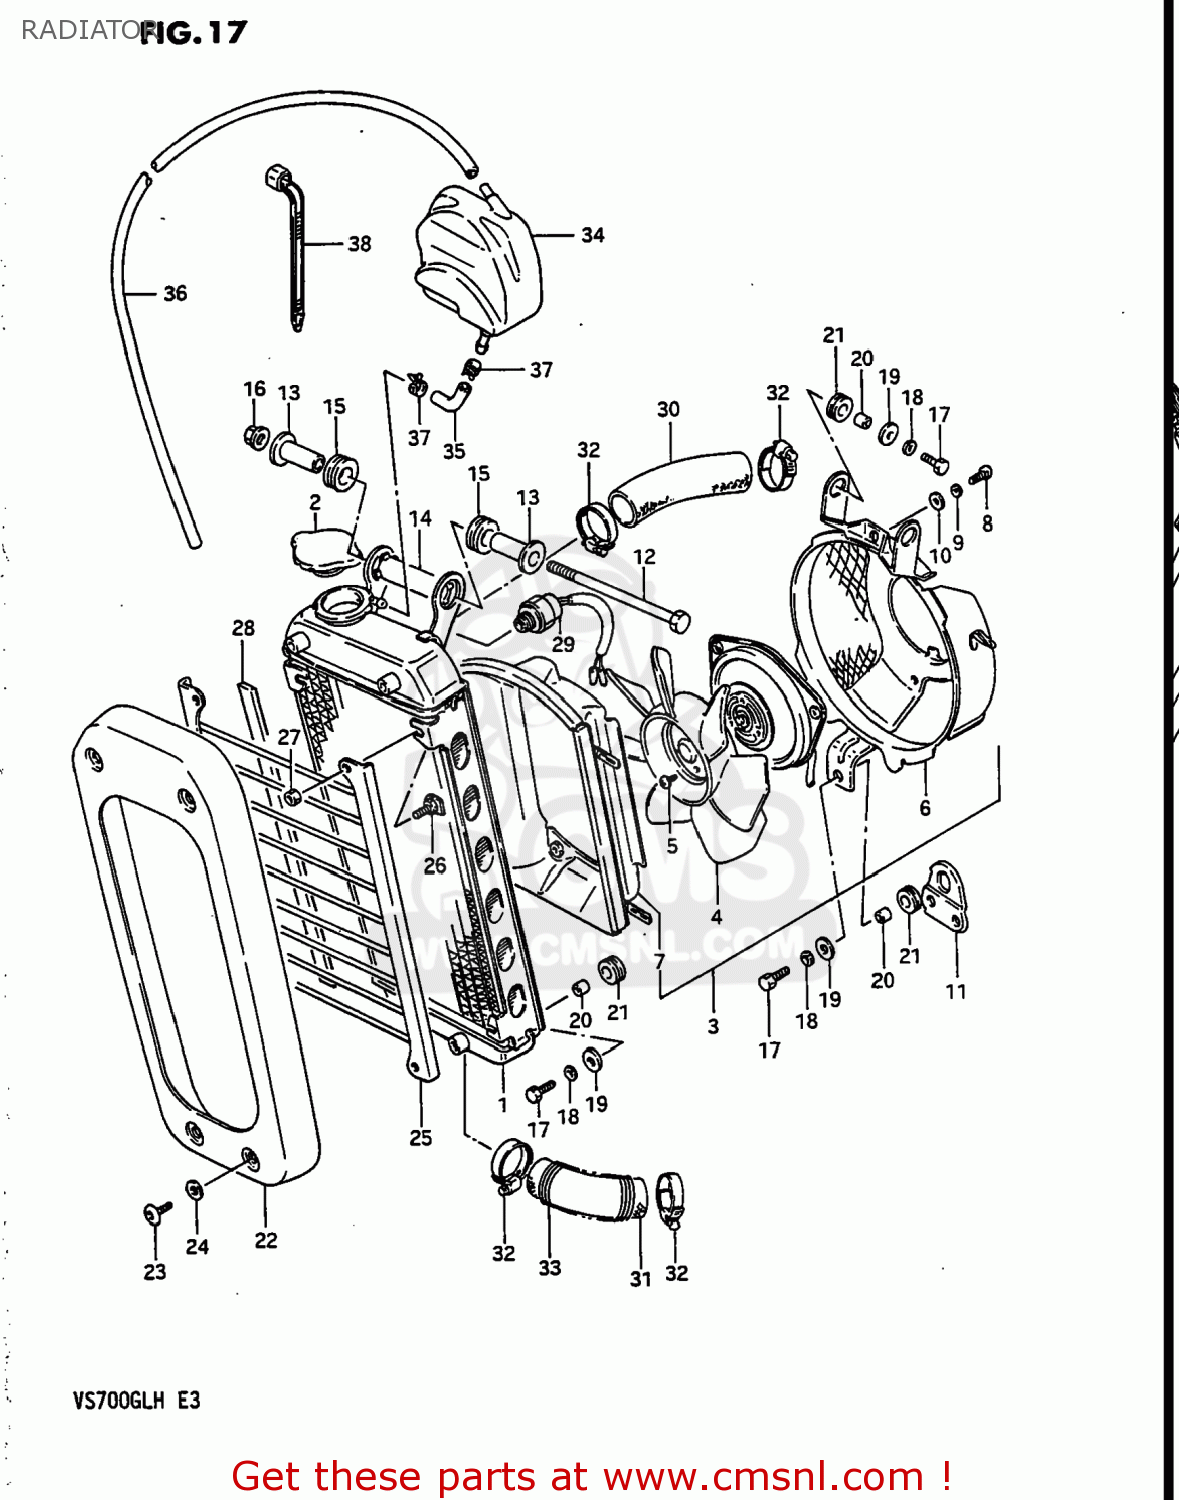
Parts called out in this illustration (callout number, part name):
1	RADIATOR COMP,WATER
2	CAP,RADIATOR
3	FAN ASSEMBLY,RADIATOR
4	FAN
5	BOLT
6	SHROUD,FAN
7	DUCT,FAN
8	SCREW 5X10
9	LOCK WASHER
10	WASHER
11	BRACKET,RADIATOR FAN
12	BOLT 10X135
13	SPACER,RADIATOR CUSHION
14	SPACER,RDTR CUSH NO.2 OUTER
15	CUSHION
16	NUT 10MM
17	BOLT 6X16
18	WASHER,LOCK
19	WASHER (6.5X18X1.6)
20	SPACER (6X9X8)
21	CUSHION
22	COVER,RADIATOR
23	SCREW
24	WASHER (6.2X14X2)
25	BUMPER COMP,RADIATOR
26	BOLT
27	NUT 5MM
28	CUSHION,RADIATOR BUMPER
29	SWITCH
30	HOSE,RADIATOR INLET
31	HOSE,RADIATOR
32	CLAMP
33	SPRING
34	TANK,RESERVOIR
35	HOSE,RESERVE TANK INLET
36	HOSE,RESERVOIR TANK OVERFLOW
37	CLIP
38	CLAMP(L:125)
39	COVER SET,RADIATOR
